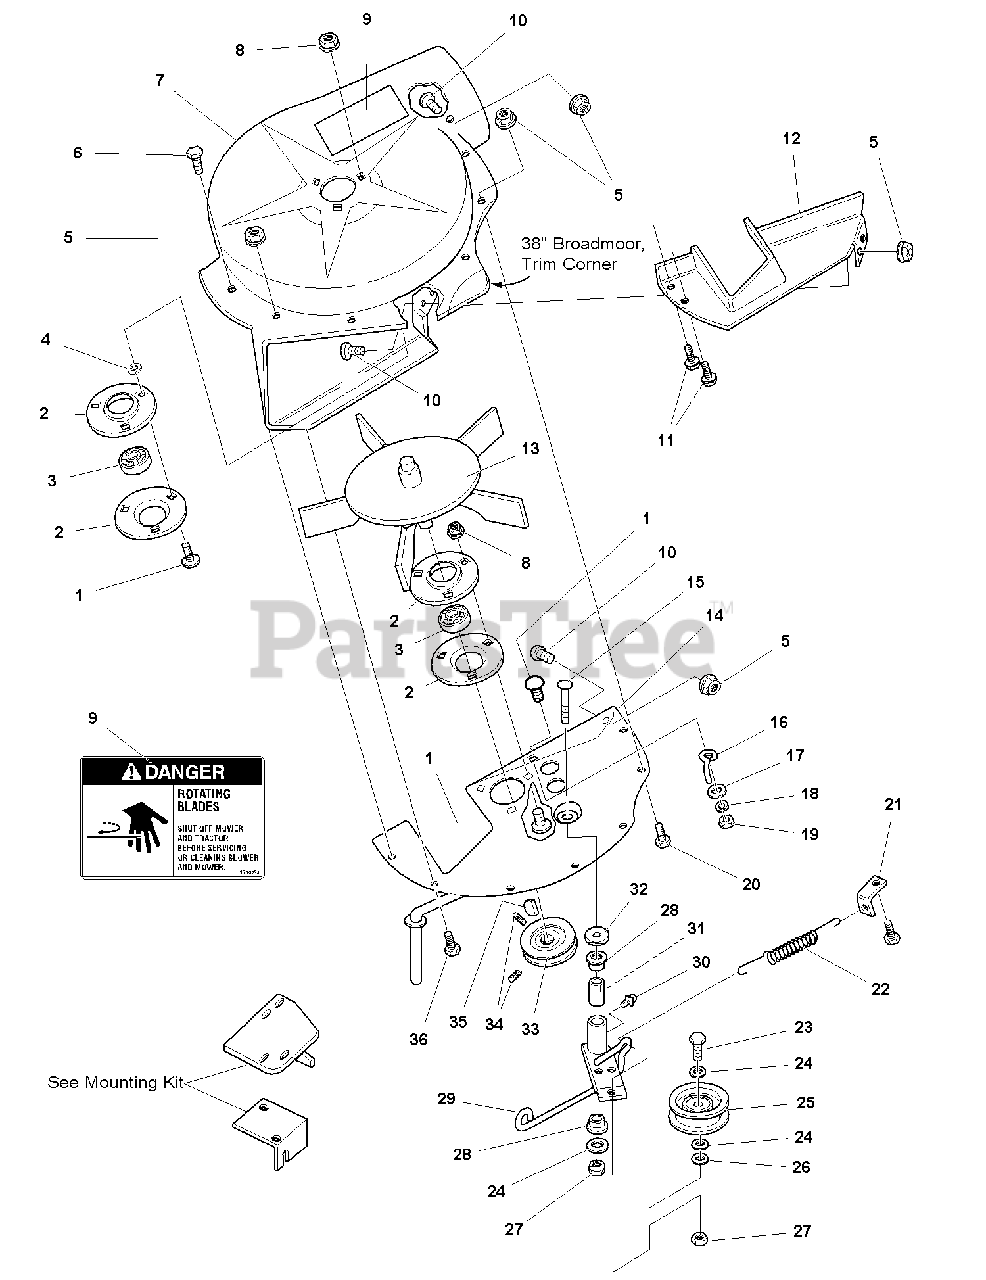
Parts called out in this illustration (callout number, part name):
1	CARRIAGE BOLT, 5/16-18 x 3/4
2	RETAINER, Bearing
4	PUSH NUT, 3/8
5	NUT, Hex, Flange Lock, 1/4-20
6	CAPSCREW, Hex, Taptite, 1/4-20 x 1/2
7	FAN HOUSING (Includes Decal)
8	NUT, Flange, Whizlock, 5/16-18
9	DECAL, Danger, Blower
10	CARRIAGE BOLT, 1/4-20 x 3/4
11	CAPSCREW, Washer Head, Plastite, 1/4-18 x 5/8
12	COVER, Bottom
13	FAN ASSEMBLY, 5 Blade
14	PLATE ASSEMBLY
15	CARRIAGE BOLT, 3/8-16 x 2-1/4
17	WASHER, Flat
18	WASHER, Spring Lock, 5/16
19	NUT, Hex, 5/16
20	CAPSCREW, Hex Head, 1/4-20 x 7/8
21	BRACKET, Anchor, Spring
22	SPRING, Tension
23	CAPSCREW, Hex Head, 3/8-16 x 1-1/4
24	WASHER, Plain
25	IDLER PULLEY ASSEMBLY
26	WASHER, Flat
27	NUT, Hex, Jam, Center Lock, 3/8-16
29	LEVER ASSEMBLY, Turbo (Includes Ref. Nos. 30 & 31)
30	FITTING, Grease
32	WASHER, Flat
33	PULLEY, Driven
34	SETSCREW, Hex, Socket Head, 5/16-18 x 5/16
35	KEY, Woodruff, Modified
36	CAPSCREW, Hex Head, 1/4-20 x 5/8
